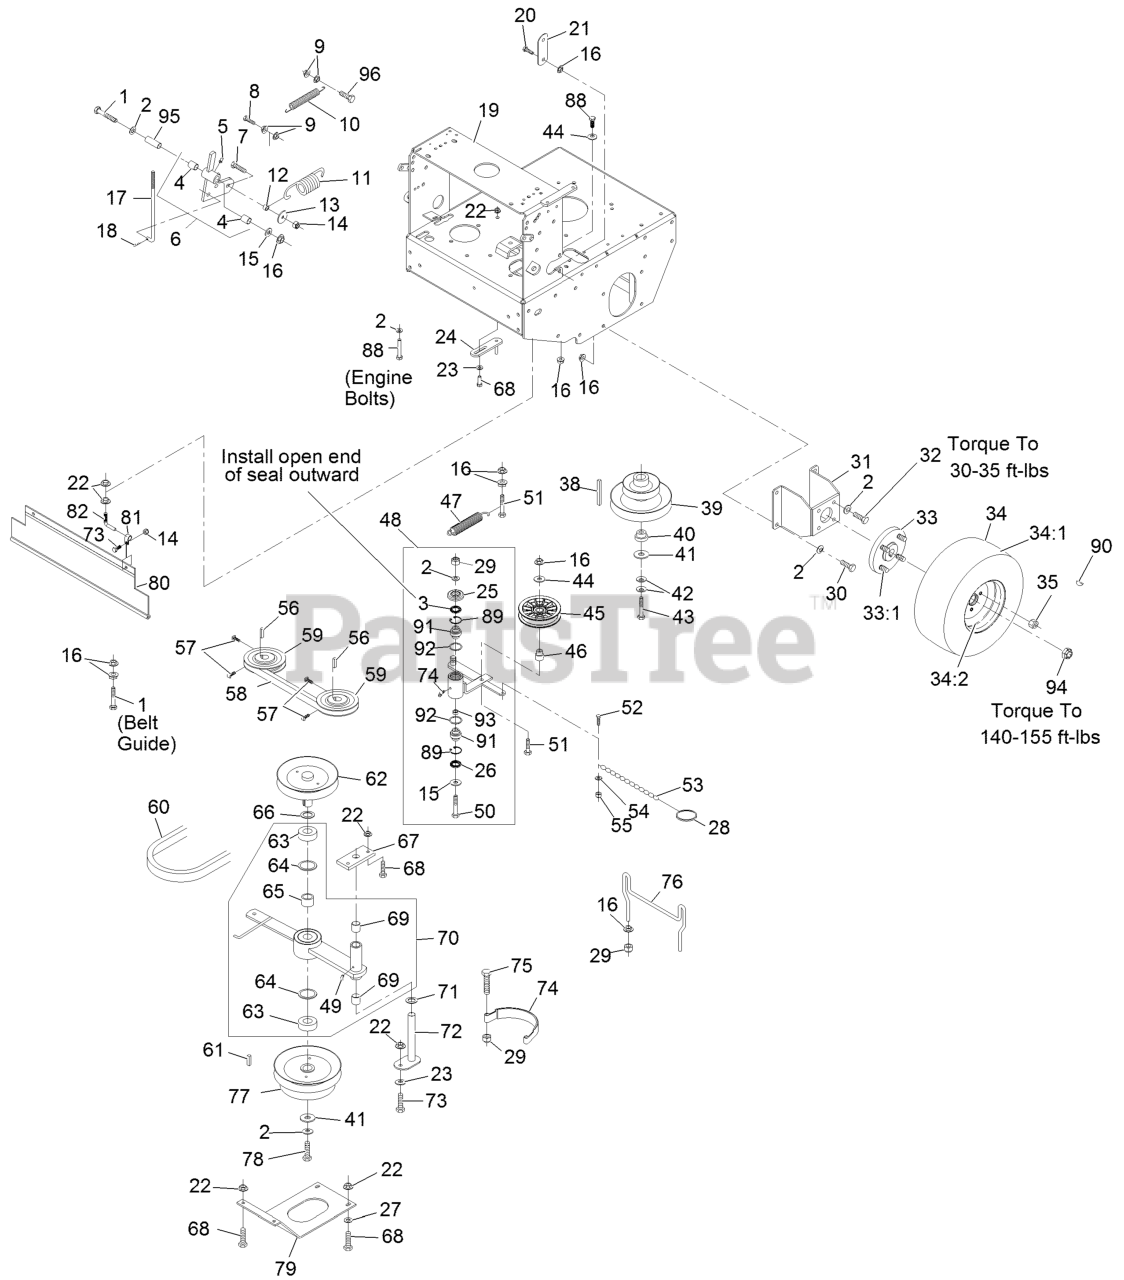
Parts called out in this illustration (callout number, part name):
1	SCREW-HH
2	WASHER-BELLEVILLE
3	SEAL-LIP, SINGLE
4	SLEEVE-BEARING
5	FITTING-GREASE
6	ASM,PIVOT W/BUSHINGS
7	SCREW-HH
8	SCREW-HH
10	SPRING,EXTENSION
11	SPRING,EXTENSION
12	SPACER,CLUTCH ANCHOR
14	NUT-LOCK, NI
15	WASHER-FLAT
16	NUT-HHF, WHIZ
17	LINKAGE,LOWER
18	PIN-COTTER
19	KIT, TTS ENG DECK
20	SCREW-HH
21	ARM-LIFT, DECK
23	WASHER-SPRING
24	GUIDE-BELT
25	GUARD-TOP
26	SEAL-LIP, DOUBLE
27	WASHER-FLAT
28	RING-SPLIT
29	NUT-LOCK, NI
30	SCREW-HH
31	WLD,MOTOR MOUNT 48&52
32	SCREW-HH
33	WHEEL HUB ASM
33:1	STUD-WHEEL
34	WHEEL AND TIRE ASM
34:1	TIRE-TURFMASTER
34:2	RIM-WHEEL
35	NUT-LUG
38	KEY,MACH 1/4X1/4X2-5/8
39	SHEAVE, DRIVE
40	BUSHING,CLUTCH KEEPER
42	WASHER-SPRING
43	SCREW-HH
44	WASHER-FLAT
45	PULLEY-IDLER, FLAT
46	BUSHING-IDLER
48	KIT,PUMP IDLER ARM TTHP
49	FITTING-GREASE
50	SCREW-HH
51	SCREW-HH
52	SCREW-HSH
53	CHAIN-LINK, TWIST
54	WASHER-FLAT
55	NUT-LOCK, NI
57	SCREW-SET, SQH
58	BELT,COG A 50.55
59	SHEAVE ASM
60	BELT,B-38.0
62	SHEAVE, W/ SHAFT
63	BEARING,CLUTCH SHAFT
64	RING-SNAP
65	SPACER,CLUTCH BEARING
66	WASHER-SPACER
67	PLATE-CLUTCH PIVOT
68	SCREW-HH
69	SLEEVE,BEARING
70	ASM,CLUTCH ARM W/BEARING
71	WASHER-SPACER
72	WLD,PIN PIVOT
73	SCREW-HH
74	BAND,BRAKE BLADE
75	SCREW-HH
76	GUIDE,BELT (PLTD)
77	SHEAVE,6.75 W/DRUM
78	SCRW,CAP HH
79	PLATE-GUARD
80	SHIELD-DRAG
81	CLIP-LOOM
82	MOUNT,DRAG SHIELD
88	SCREW-HH
89	RING-SNAP
90	KEY-WOODRUFF
91	BEARING-SPHERICAL
94	NUT-LOCK
95	BUSHING
96	SCREW-HH
